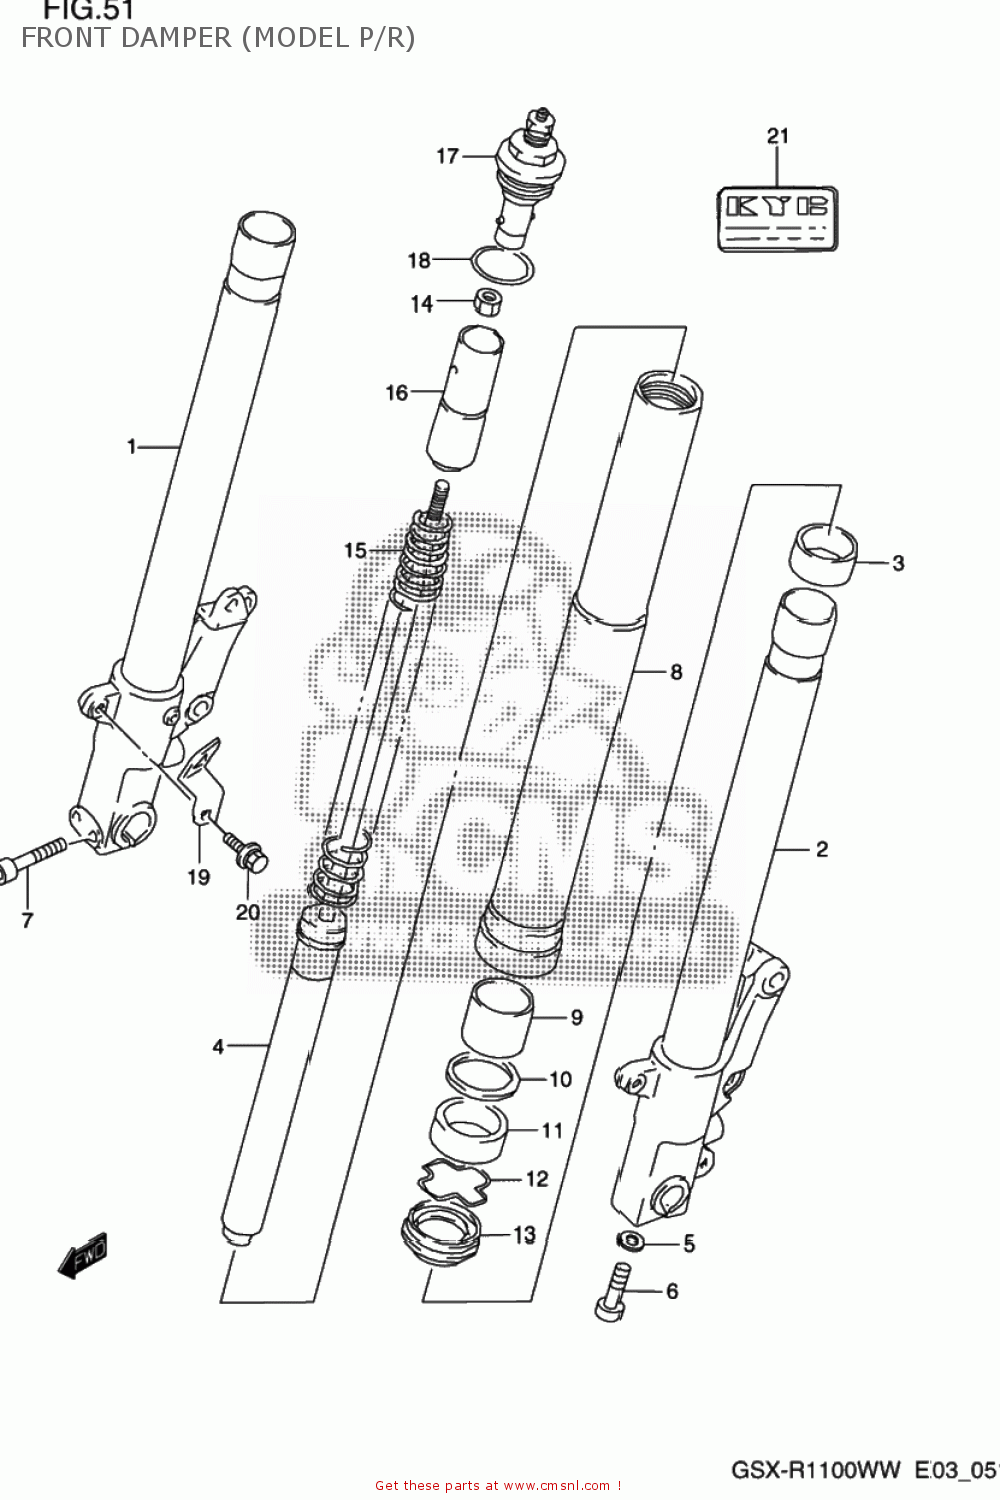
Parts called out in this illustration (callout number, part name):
1	TUBE,INNER,R
2	TUBE,INNER,L
3	PISTON
4	CYLINDER ASSY
5	GASKET,CYLINDER (NAS)
6	BOLT,OIL LOCK PIECE,12X22
7	BOLT
8	TUBE,OUTER
9	10
10	WASHER,FORK OIL SEAL
11	OIL SEAL,FRONT FORK
12	RING,OIL SEAL STOPPER
13	SEAL,DUST
14	NUT,ROD
15	SPRING,MAIN
16	SPACER,SPRING
17	CAP ASSY,FORK
18	O RING
19	PLATE,FRONT FENDER,LEFT
20	BOLT
21	LABEL
